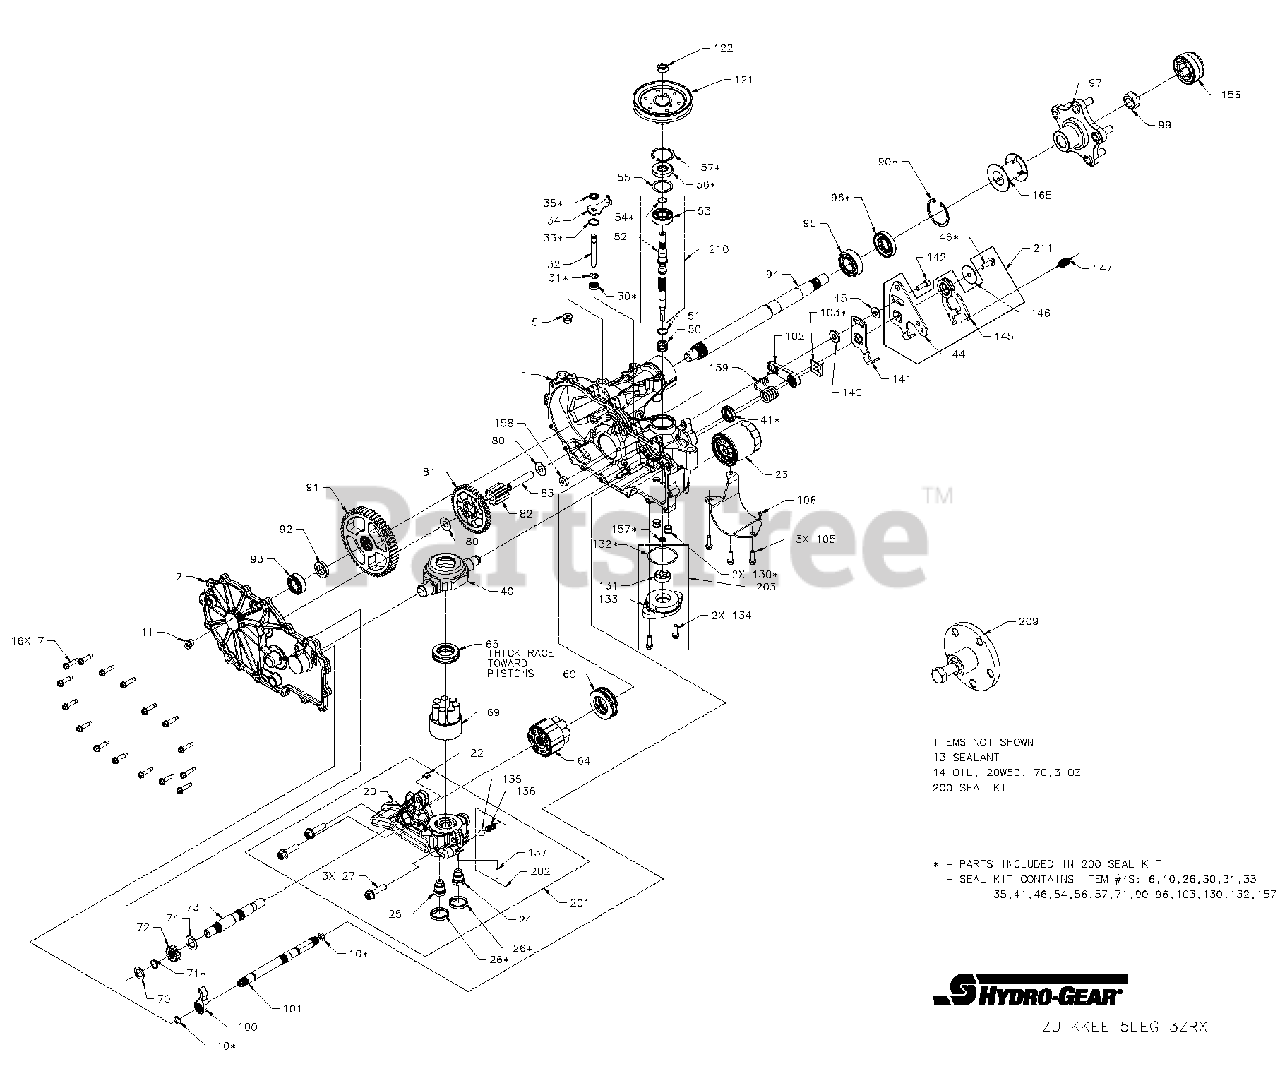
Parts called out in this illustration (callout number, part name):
23	FILTER, OIL
30	SEAL, LIP .375 X .75 X .25
31	RING, RET .375 EXTRNL
35	RING, RTNG .375 EXT
40	TRUNNION, SWASHPLATE
41	SEAL, LIP 12 X 32 X 7
46	TWHCS 5/16-24 X 1.00 (PATCH)
51	WASHER - FLAT .59 X .79 X .04
55	WASHER 1.23 X 1.56 X .04
56	SEAL, LIP 17 X 40 X 7
57	RING, RETAINING
80	WASHER .5 X 1.0 X .03
95	BRG, BALL 35.4 X 52 X 15
96	SEAL, LIP 1.000 X 2.049 X .375
99	NUT, HEX LOCK 3/4-16
122	NUT, HEX JAM 1/2-20 W/PATCH
132	O-RING, -137, 0.103 X 2.050
146	WASHER, .343 X 1.500 X .062
147	SPRING, EXTNSN RTN - 34 LBS
